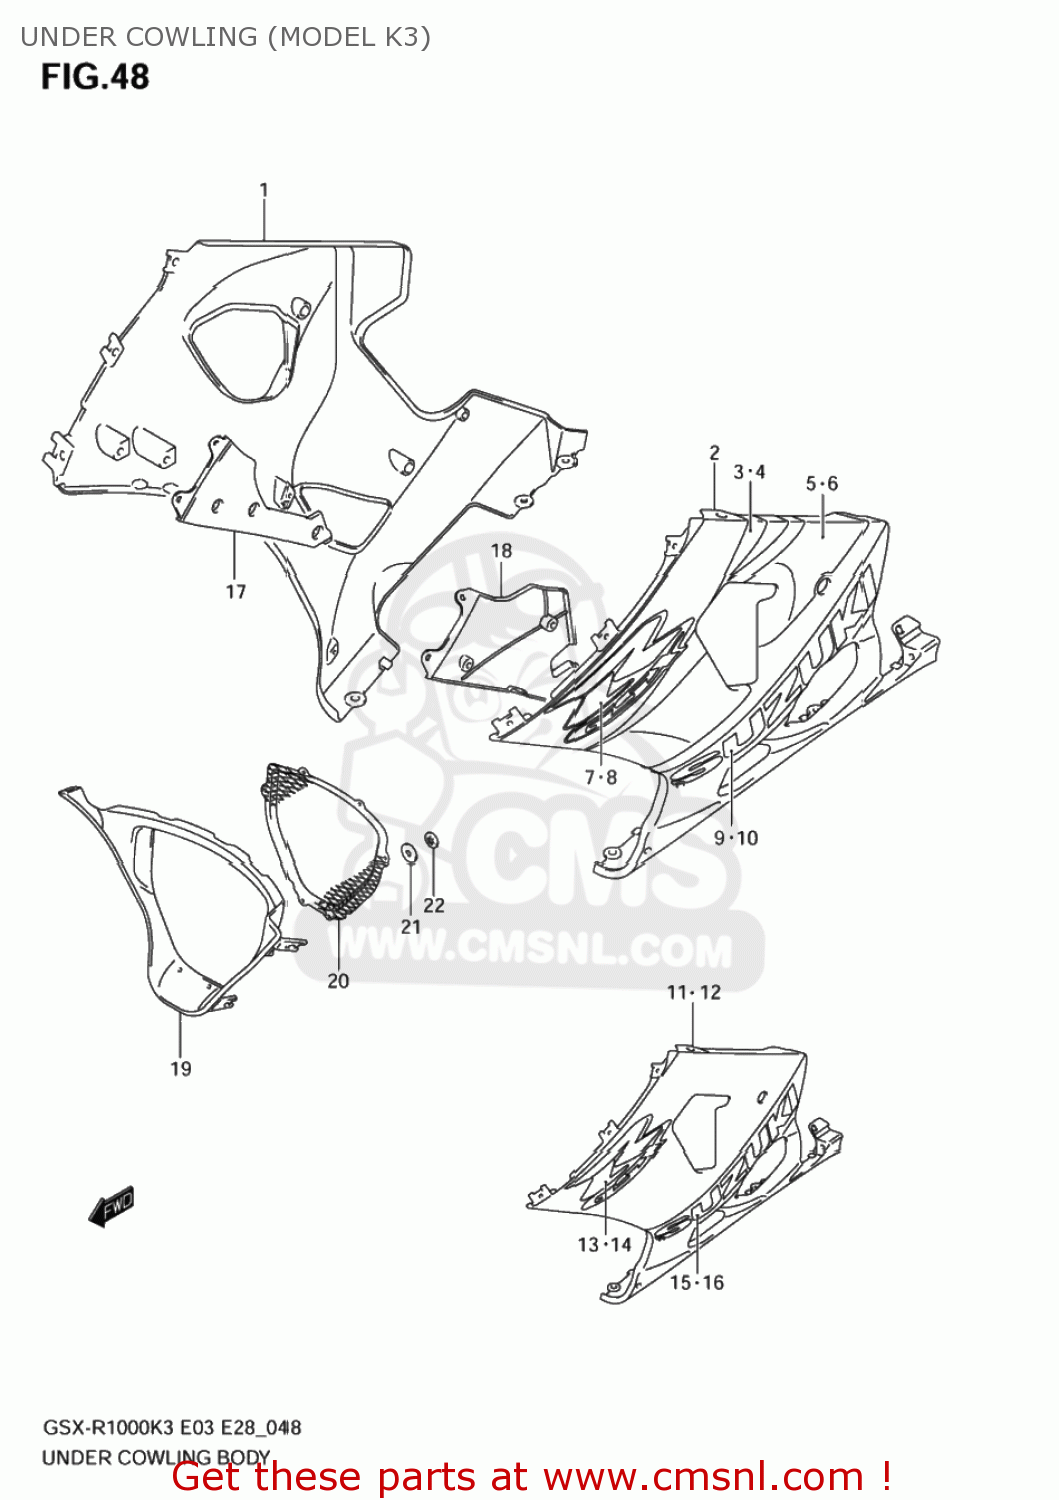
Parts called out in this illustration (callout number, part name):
1	COWLING ASSY,UNDER,R
2	COWLING ASSY,UNDER,L
3	TAPE,COWL UPR,R
4	TAPE,COWL UPR,L
5	TAPE SET,COWL MIDDLE,R
6	TAPE SET,COWL MIDDLE,L
7	EMBLEM,GSXR,R
8	EMBLEM,GSXR,L
9	EMBLEM,SUZUKI,R
10	EMBLEM,SUZUKI,L
11	COWLING ASSY,UNDER,R
12	COWLING ASSY,UNDER,L
13	EMBLEM,GSXR,R
14	EMBLEM,GSXR,L
15	EMBLEM,SUZUKI,R
16	EMBLEM,SUZUKI,L
17	COWLING,UNDER INNER,R
18	COWLING,UNDER INNER,L
19	COWLING,UNDER CTR
20	COWLING,UNDER CTR
21	CUSHION
22	NUT
